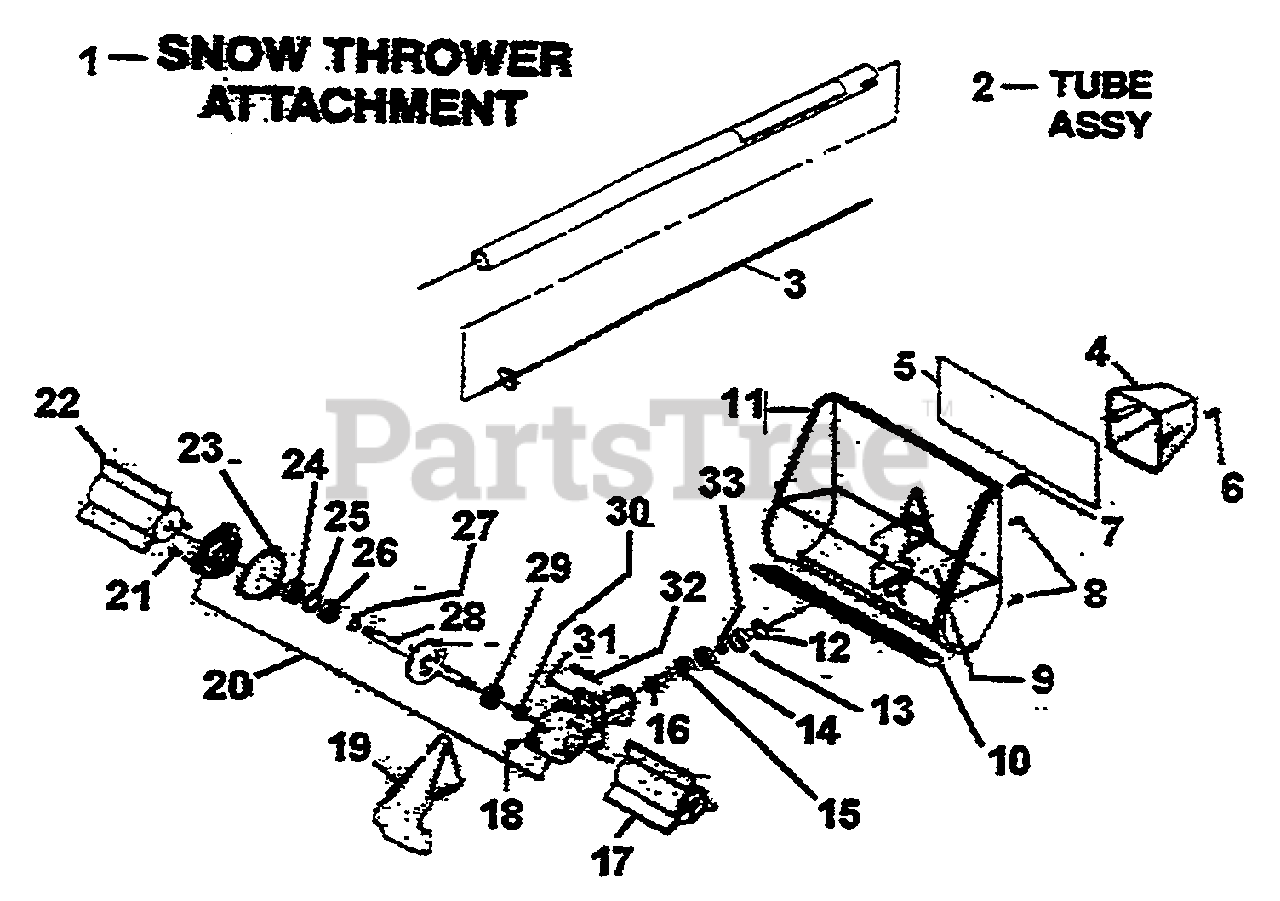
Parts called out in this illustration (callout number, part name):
2	TUBE ASSY
3	FLEX CABLE
9	PLATE
10	SCRAPER BAR
12	SNAP RING
15	BEARING
16	PINION GEAR
17	ROTOR R.H.
20	GEAR CASE ASSY
22	ROTOR L.H.
28	SHAFT & GEAR
33	SNAP RING
